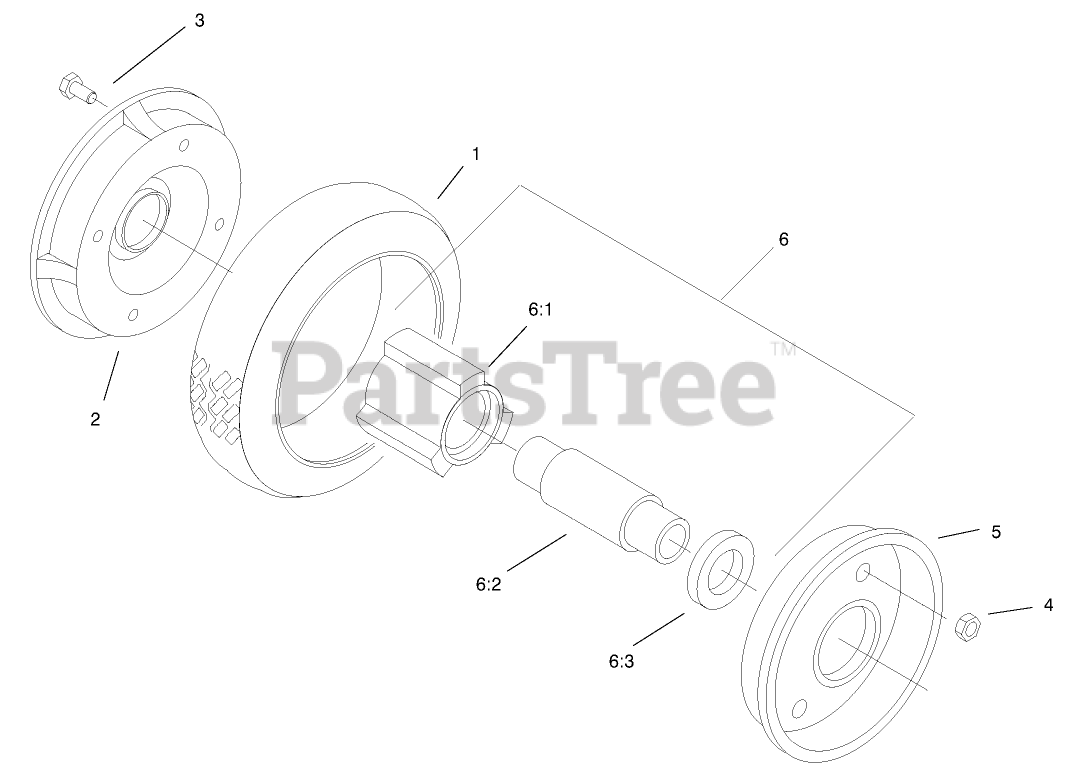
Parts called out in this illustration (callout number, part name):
3	SCREW-HH
4	NUT-LOCK, NI
6	Hub Brg ASM
6:1	HUB-BEARING
6:2	SPACER-BEARING
6:3	BEARING-WHEEL
